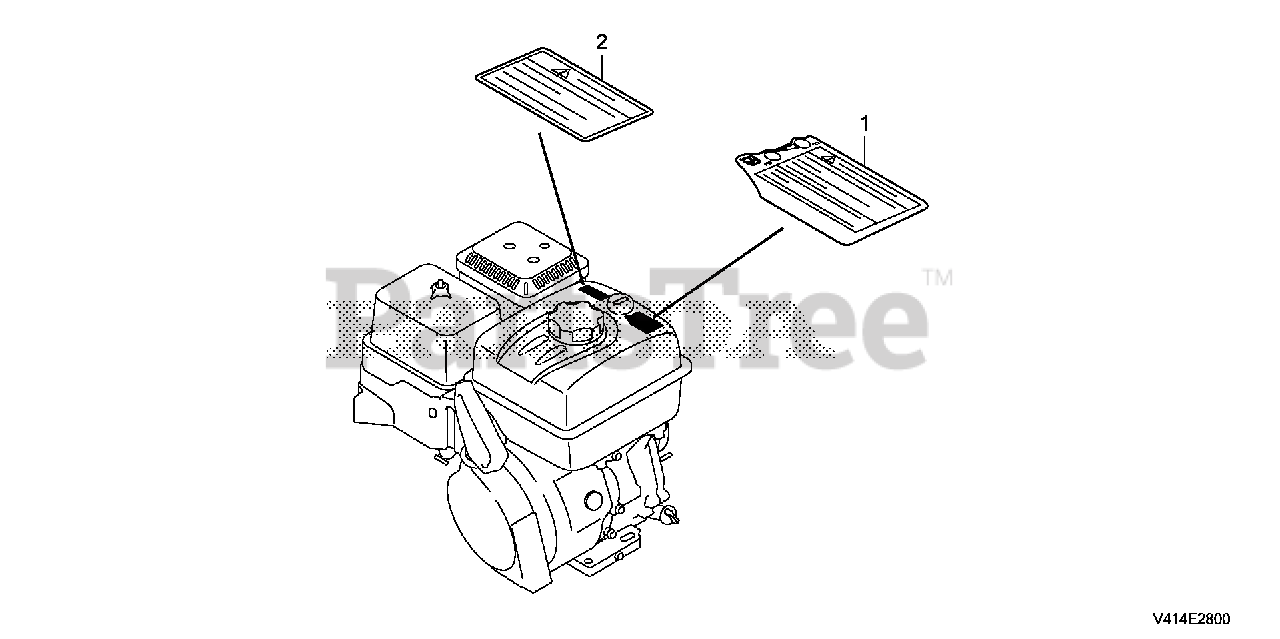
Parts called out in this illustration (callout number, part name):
1	MARK, FUEL WARNING COMBINATION (ENGLISH)
2	MARK, EX. CAUTION (ENGLISH)
2	MARK, EX. CAUTION (FRENCH)
